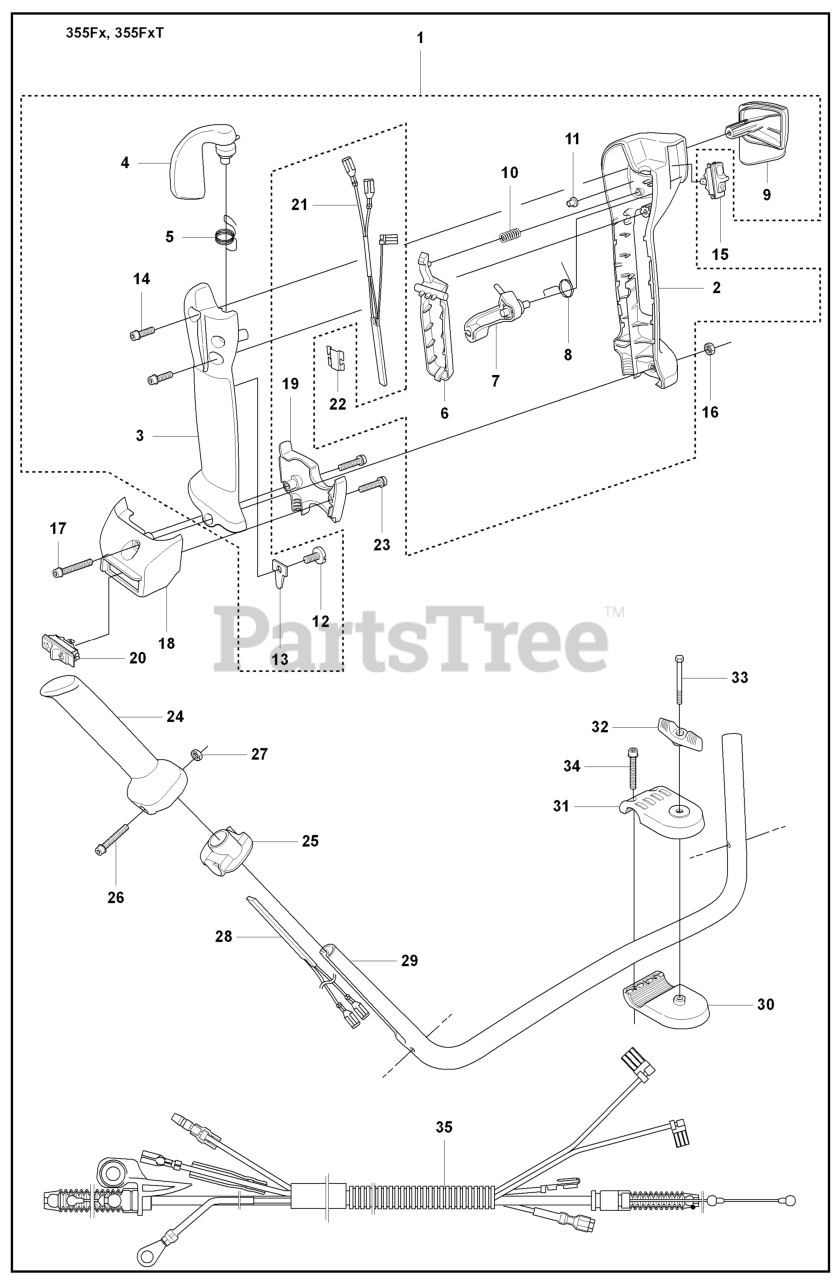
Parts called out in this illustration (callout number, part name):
2	HANDLE
3	HANDLE
4	THROTTLE TRIGGER
5	RP SPRING
6	THROTTLE LOCK
15	STOP BUTTON
16	NUT M6M M5
17	SCREW
18	HOLDER
19	HOLDER
20	SWITCH (G)
21	HEATING ELEMENT
23	SCREW
27	NUT M6M M5
28	HEATING ELEMENT
29	%HANDLE
30	HANDLE HOLDER LOWER
31	HANDLE HOLDER UPPER
33	%SCREW
35	WIRING
